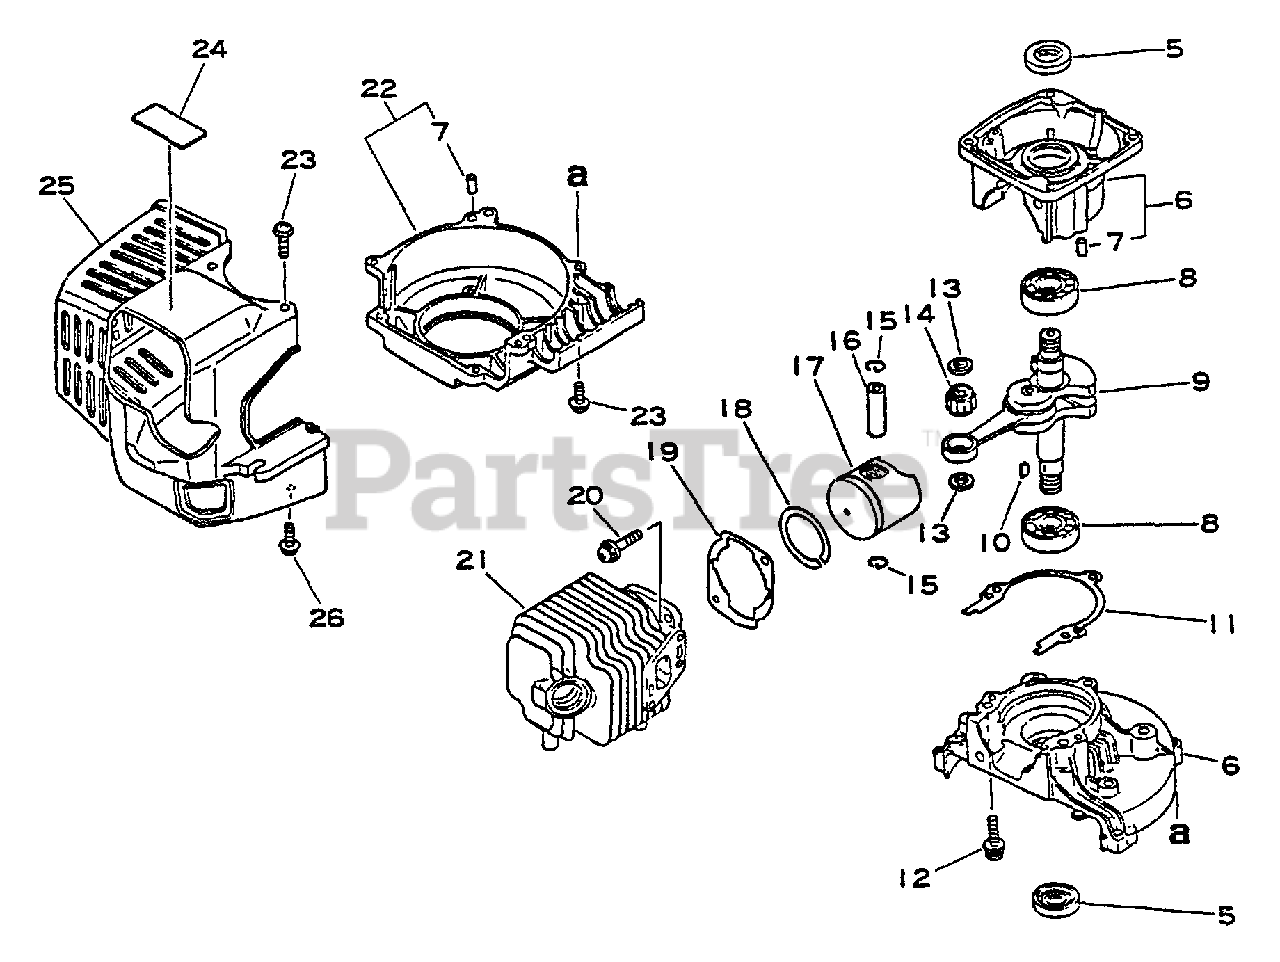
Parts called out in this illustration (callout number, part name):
5	SEAL, OIL 12
6	CRANKCASE KIT
7	PIN, LOCATING 4
8	BEARING, BALL - 6201 C3
9	CRANKSHAFT
10	KEY, WOODRUFF
11	GASKET, CRANKCASE
12	SCREW 5×30
13	WASHER, THRUST
14	BEARING, NEEDLE
15	RING, SNAP
16	PIN, PISTON
17	PISTON
18	RING, PISTON
19	GASKET, CYLINDER
20	SCREW 5×25
21	CYLINDER
22	COVER, FAN
23	SCREW 4×14
24	LABEL
25	COVER, ENGINE - ORANGE
26	SCREW 4×20
